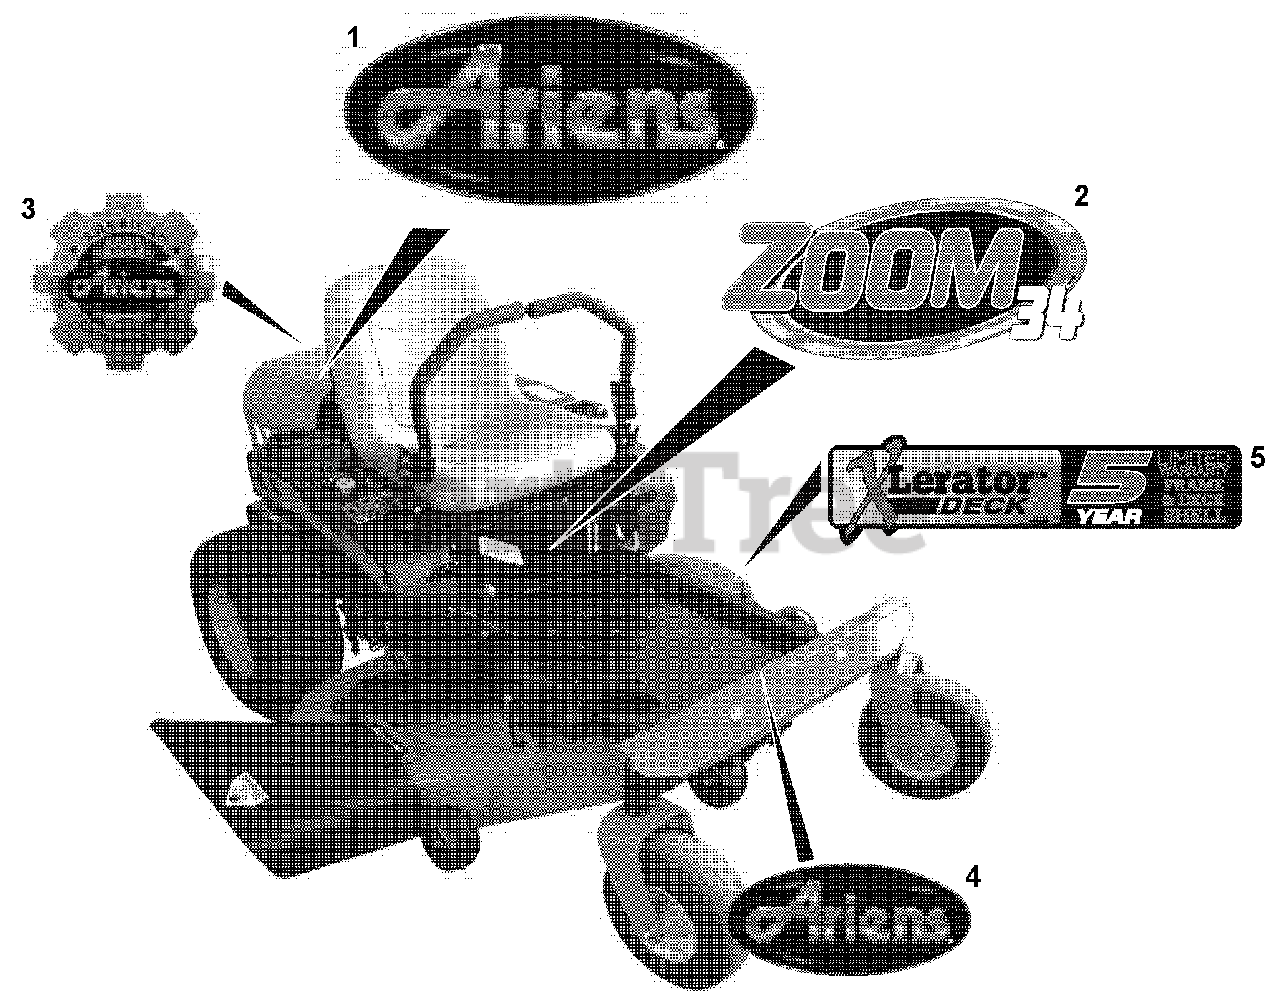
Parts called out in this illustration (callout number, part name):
1	DECAL, ARIENS JEWEL
2	DECAL, ZOOM 34
2	DECAL, ZOOM42
3	Decal, Ariens Heritage, Large
4	DECAL, ARIENS JEWEL
5	DECAL,DECK WARRANTY-XCEL ARIEN
